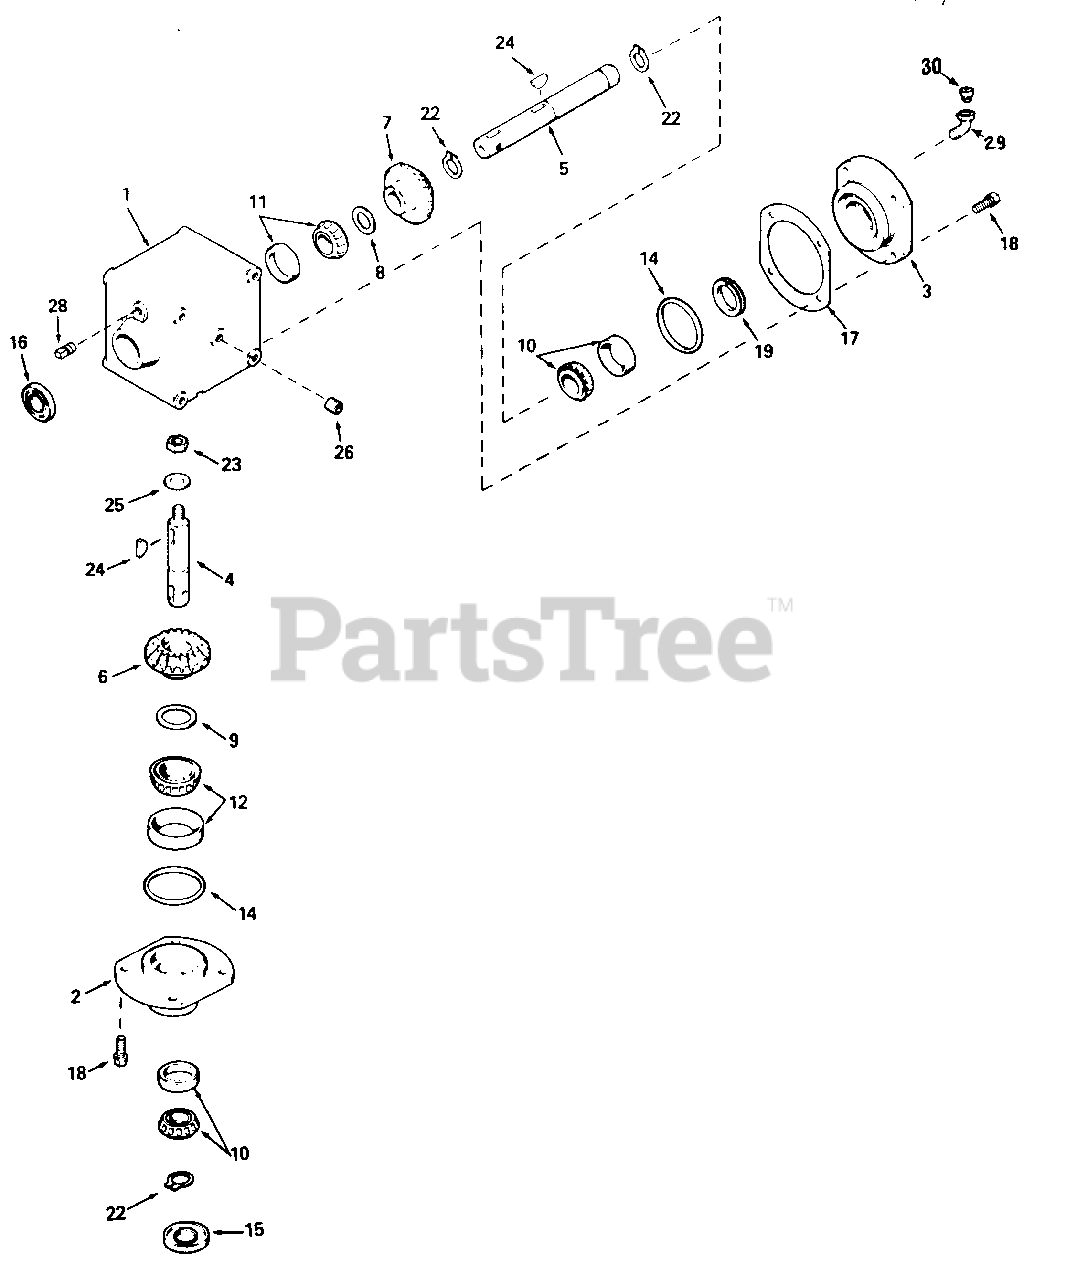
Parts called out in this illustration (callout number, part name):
1	Housing
2	Retalner Cap
3	Retainer Cap
5	Output Shaft
6	Bevel Gear, 25 Teeth
7	Bevel Gear, 926 Teeth
8	Shlm, 1 1/2" OD
9	ShLm, 2" OD
10	Bearing & Cup Assembly
11	Bearing & Cup Assembly
12	Bearing & Cup Assembly
17	Cap Retalner Shim
18	Hex Screw, 5/16-18 x 1"
22	Retaining Rlng
23	Jam Nut, 3/4-16
24	Woodruff Key
25	Flatwasher
26	Pipe Plug, 1/4-18 0
28	Pipe Plug, 1/8-27 0
29	Street Elbow, 1/8" x 90ø
